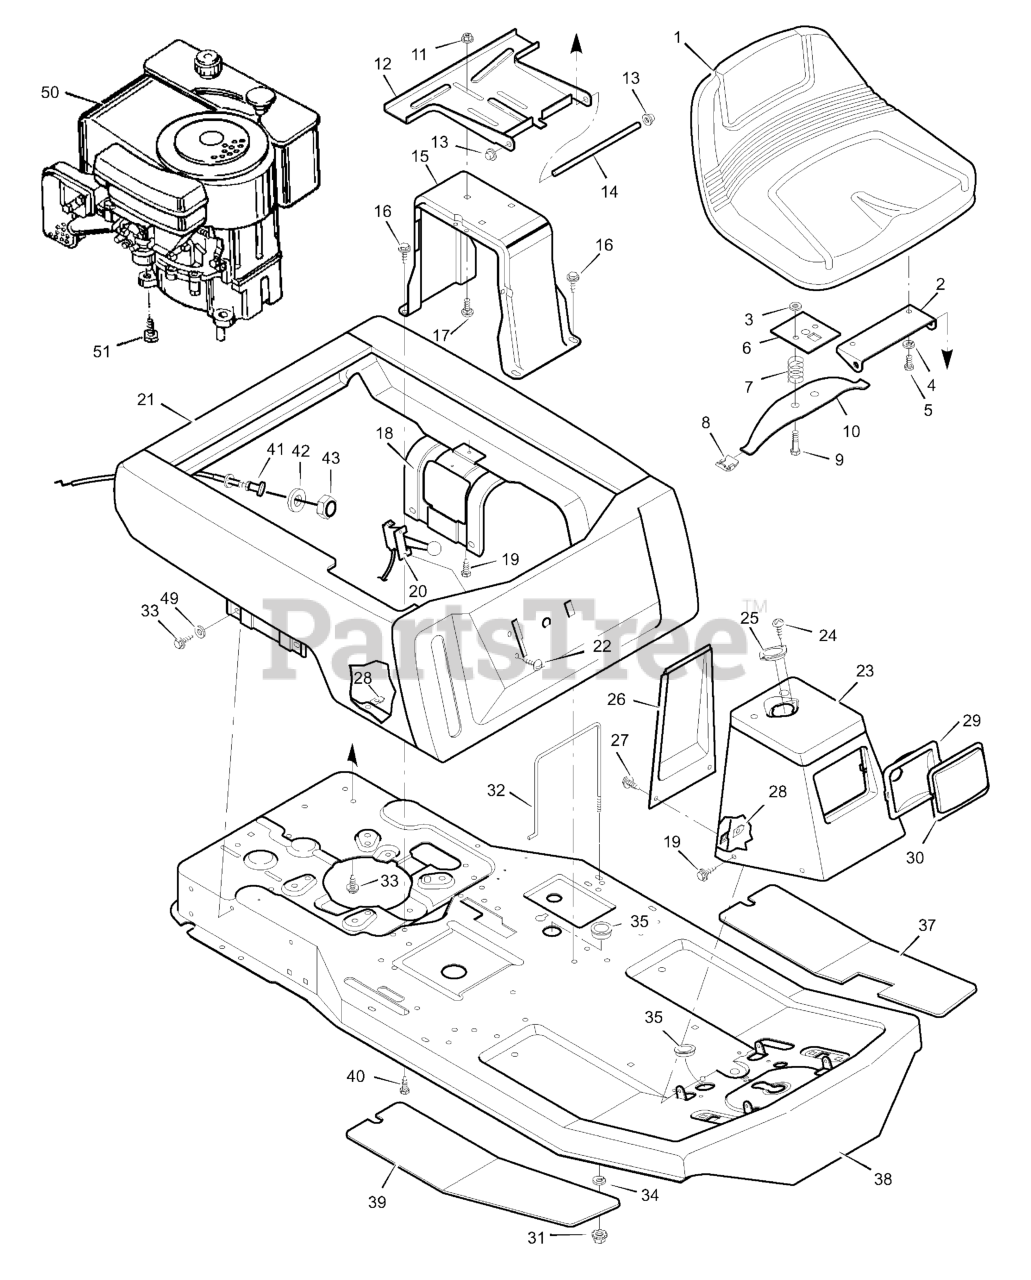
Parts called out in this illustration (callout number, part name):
2	Hinge, Seat
3	Retainer
4	Lockwasher
5	Bolt, Hex
6	Plate, Seat Switch
7	Spring, Compression
8	Glide, Seat Spring
9	Bolt, Shoulder
10	Spring, Seat
11	Locknut, Flange
12	Bracket, Seat Pivot
13	Cap, Push On
14	Rod, Seat Hinge
15	Support, Seat
17	Bolt, Carriage
18	Support, Body
20	Throttle Control
23	Console Assembly
25	Bearing, Steering Post
26	Console, Plate
29	Reflector
31	Locknut
32	Clamp, Battery
35	Grommet
37	Mat, Left
38	Frame Assembly
39	Mat, Right
42	Washer
49	Washer
50	Engine *
51	Bolt, Engine Mount
